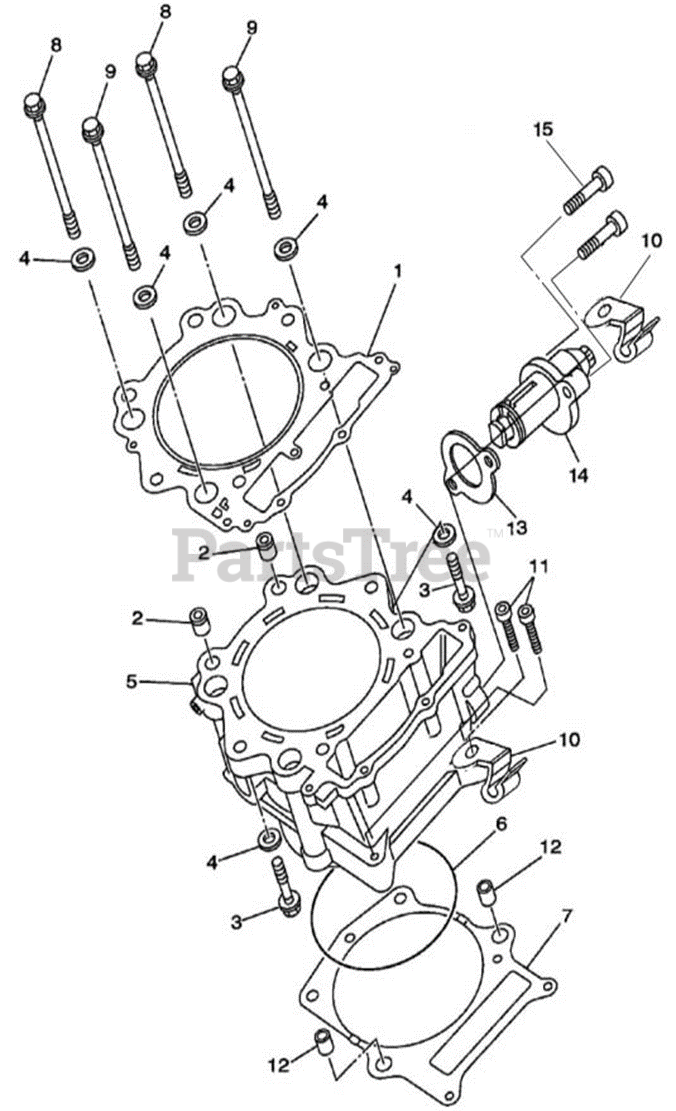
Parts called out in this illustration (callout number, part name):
1	CYLINDER HEAD GASKET
2	DOWEL PIN 12X16
3	CYLINDER BOLT M9X1.25X39
4	WASHER 10X19X2
5	CYLINDER BODY ASSEMBLY
6	O-RING 105.7X2.8
7	CYLINDER BODY GASKET
8	CYLINDER BOLT M10X1.25X121
9	CYLINDER BOLT M10X1.25X128
10	WIRE CLAMP
11	HEX HEAD CAP SCREW M6X40
12	DOWEL PIN 14X16
13	TENSIONER GASKET
15	HEX HEAD CAP SCREW M6X25
